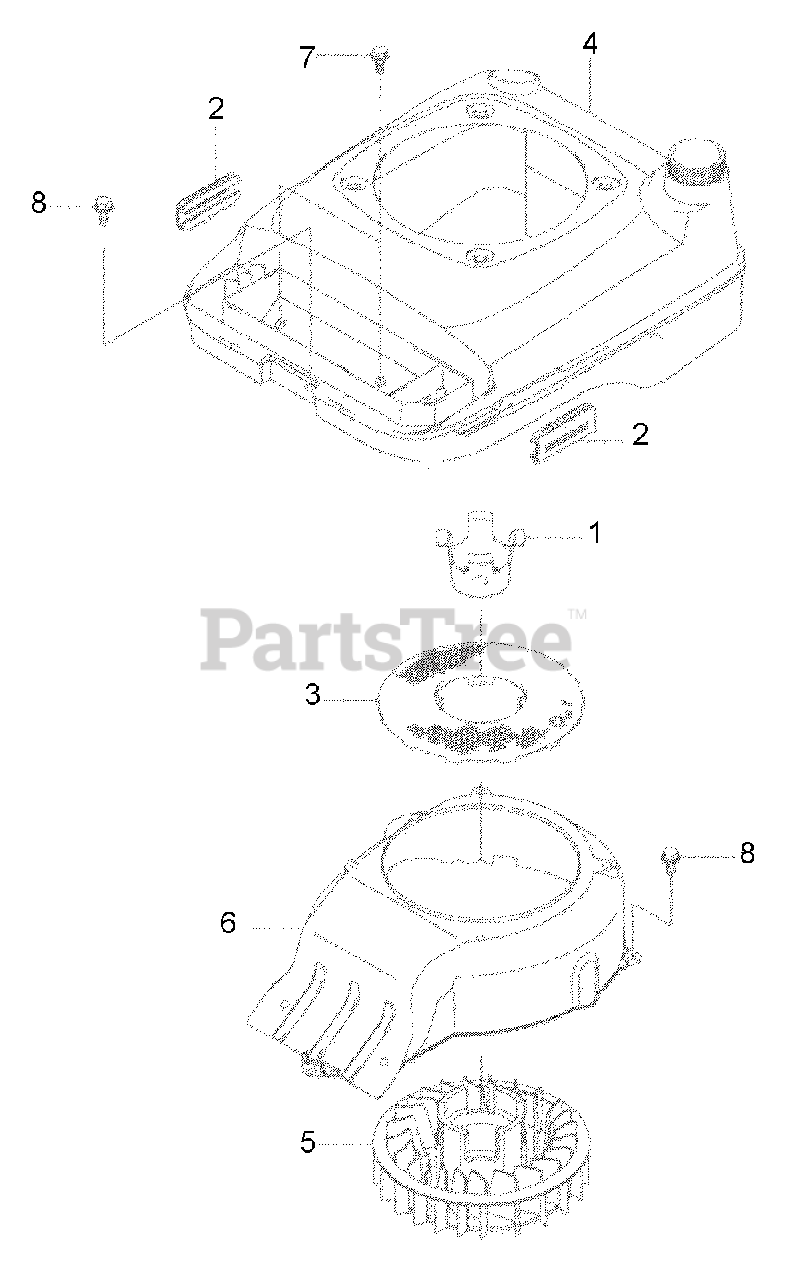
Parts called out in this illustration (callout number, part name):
3	Screen
4	Cover
5	Fan
6	Fan Housing
8	Flanged Bolt
